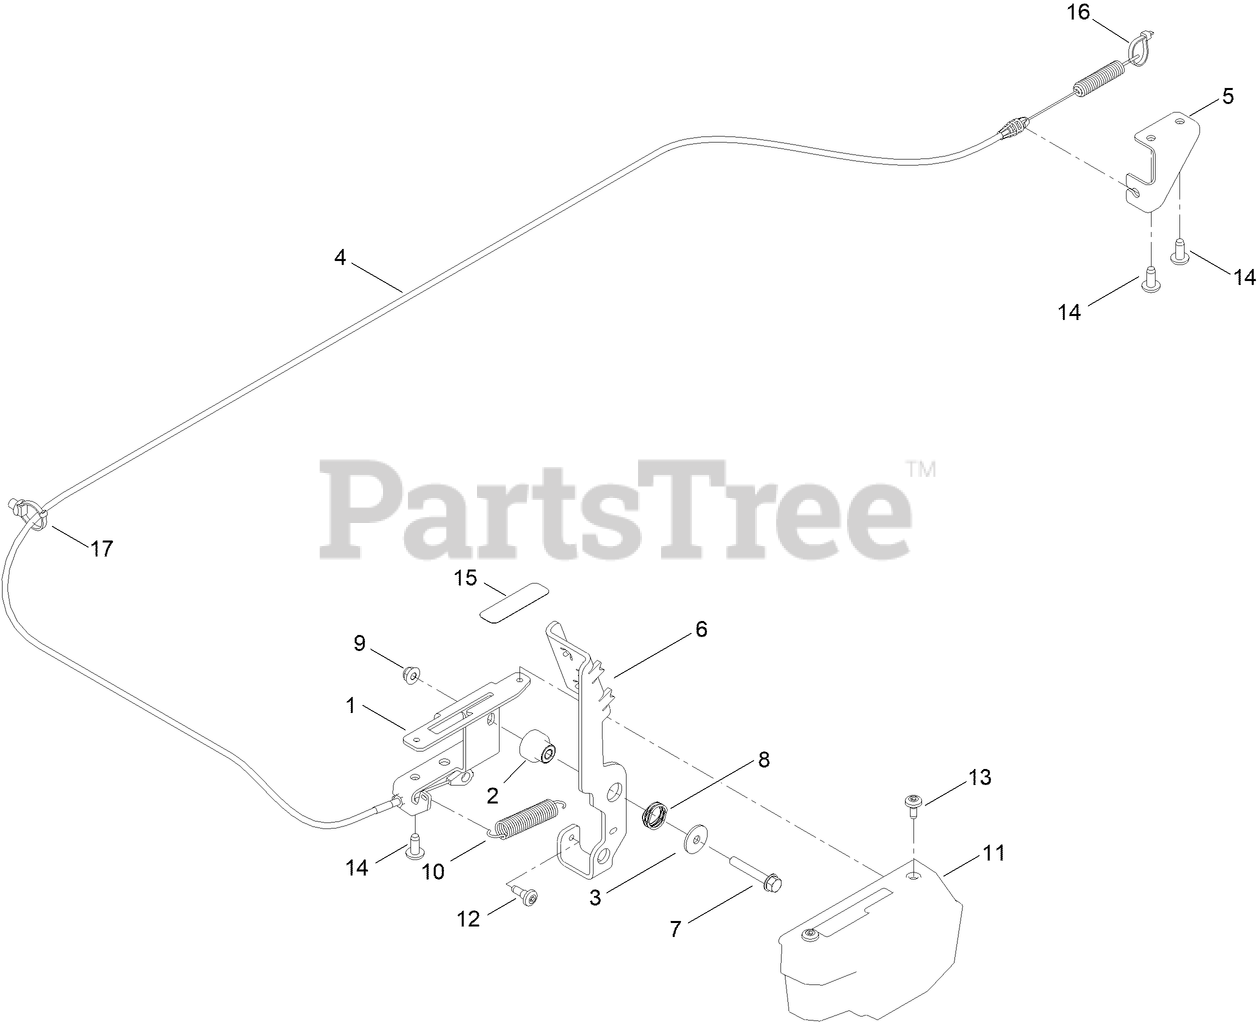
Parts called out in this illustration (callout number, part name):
1	BRACKET-PEDAL, BRAKE
2	BUSHING-FLANGE
3	WASHER-PIVOT
4	CABLE-BRAKE
5	BRACKET-CABLE, BRAKE
6	PEDAL-BRAKE
7	SCREW-HHF
8	WASHER-WAVE
9	NUT-HF
10	SPRING-PEDAL, RETURN
11	COVER-BRAKE, PARKING
12	SCREW-SHOULDER
13	SCREW-SHOULDER
15	DECAL-BRAKE, PARKING
16	TIE-CABLE
17	CLIP-TIE
